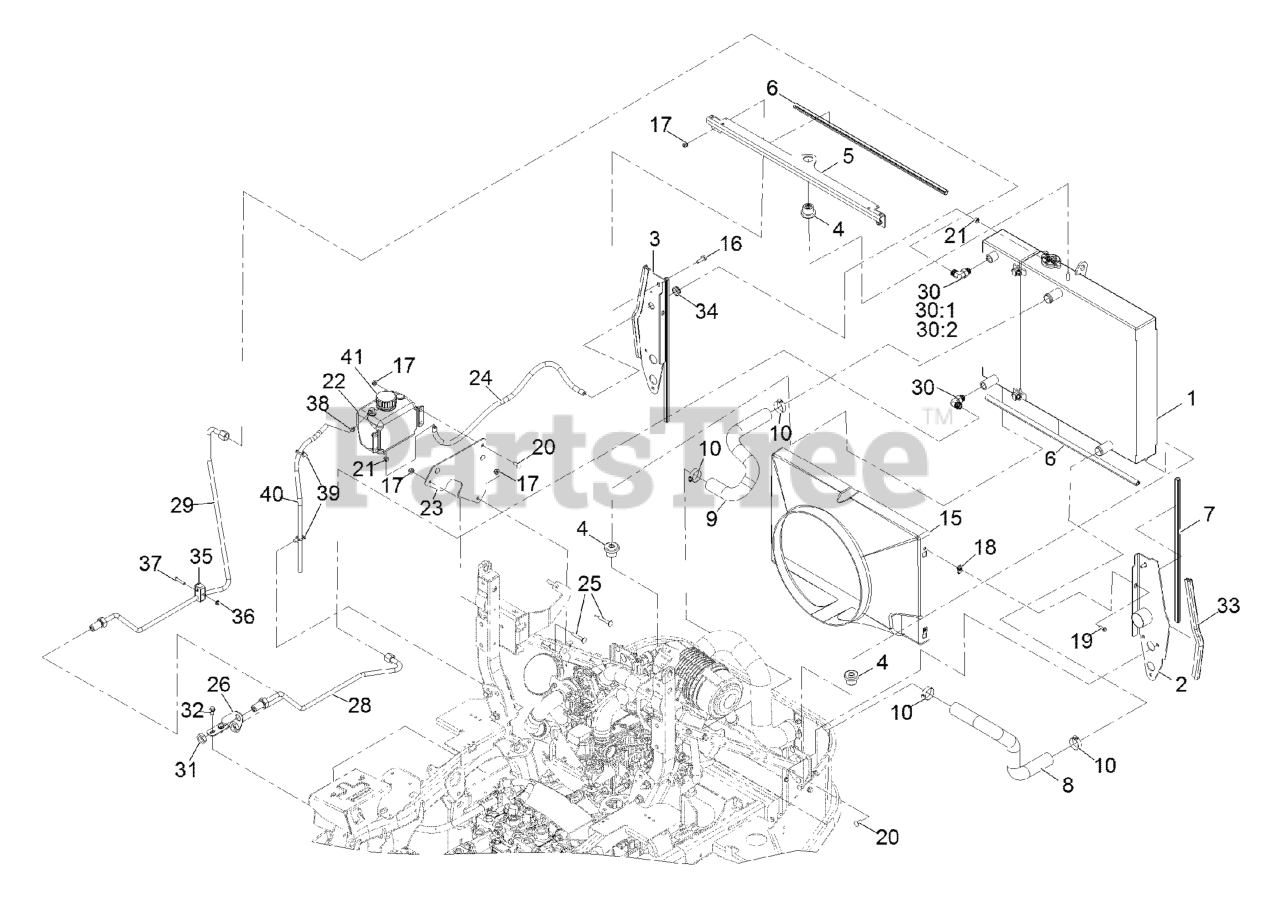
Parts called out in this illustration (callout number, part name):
1	COOLING ASM
2	SUPPORT-RADIATOR, LH
3	SUPPORT-RADIATOR, RH
4	MOUNT-ISOLATOR
5	BRACKET-COOLING, TOP
6	SEAL-BULB
7	SEAL-BULB
8	HOSE-RADIATOR, LOWER
9	HOSE-RADIATOR, UPPER
10	CLAMP-HOSE
15	SHROUD-FAN
16	SCREW-HHF
17	NUT-HF, NI
19	SCREW-HWH
20	SCREW-CARR
21	CLAMP-HOSE
22	TANK-OVERFLOW, W/CAP
23	BRACKET-BOTTLE
25	BOLT-CARR
26	BRACKET-BULKHEAD
28	HYDRAULIC TUBE ASM
29	HYDRAULIC TUBE ASM
30	FITTING-ELBOW, 90 DEG
30:1	O-RING
30:2	O-RING
31	NUT-BULKHEAD
32	Screw-HWH 5/16-18 X 3/4 Tf
33	SEAL-BULB
34	GROMMET
35	CLAMP-TWIN
37	SCREW-HH
38	CLAMP-HOSE
39	CLIP-TIE
40	HOSE-FUEL
41	CAP-W/TETHER
